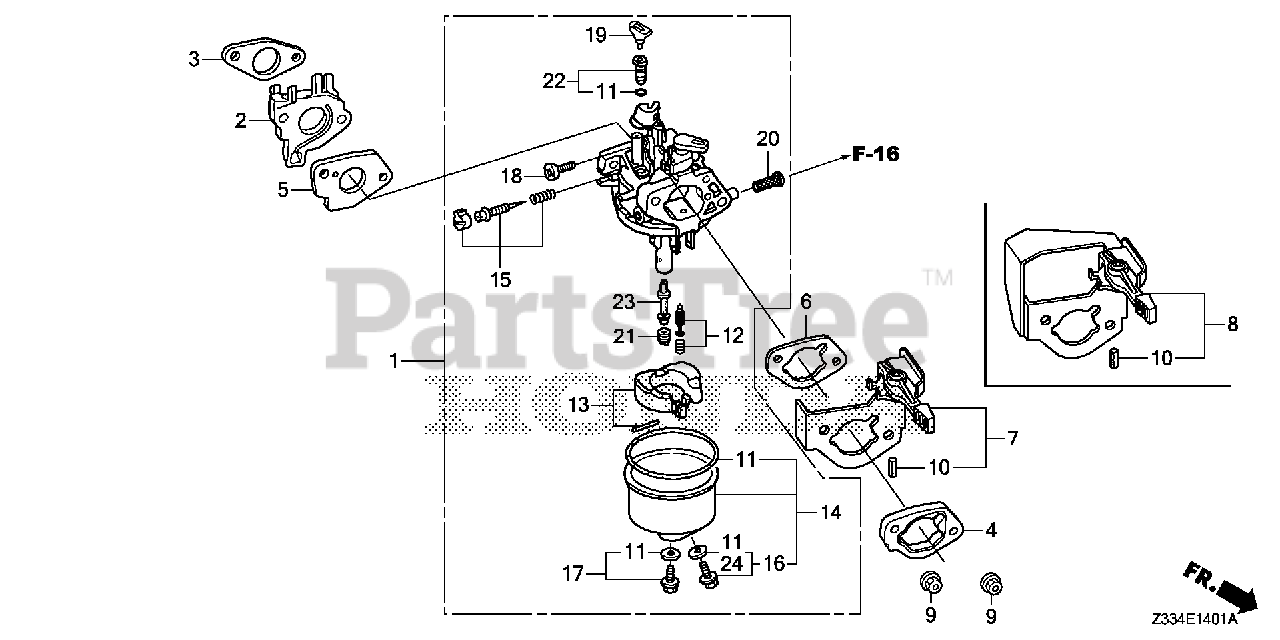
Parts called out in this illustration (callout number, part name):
1	CARBURETOR ASSY. (BE72V A)
2	INSULATOR, CARBURETOR
3	GASKET, INSULATOR
4	SPACER, CARBURETOR
5	GASKET, CARBURETOR
6	GASKET, AIR CLEANER
7	BASE, CHOKE
9	NUT, FLANGE (6MM)
10	PIN, SPRING (2X12)
11	GASKET SET
12	VALVE SET, FLOAT
13	FLOAT SET (CARBURETOR NO.)
14	CHAMBER SET, FLOAT
15	SCREW SET (Honda Code 4219879). (CARBURETOR NO.)
16	SCREW SET, DRAIN (Honda Code 1672187). (CARBURETOR NO.)
17	SCREW SET
18	SCREW, THROTTLE STOP
19	COLLAR, SET
20	SCREEN, FUEL STRAINER
21	JET, MAIN (#82)
21	JET, MAIN (#85) Use up to Engine SN BE81B B.
21	JET, MAIN (#88) Use up to Engine SN BE81B B.
22	JET SET, PILOT (#38)
23	NOZZLE, MAIN
24	WASHER, PLAIN (6.2X10.7 DRAIN) (CARBURETOR NO.)
